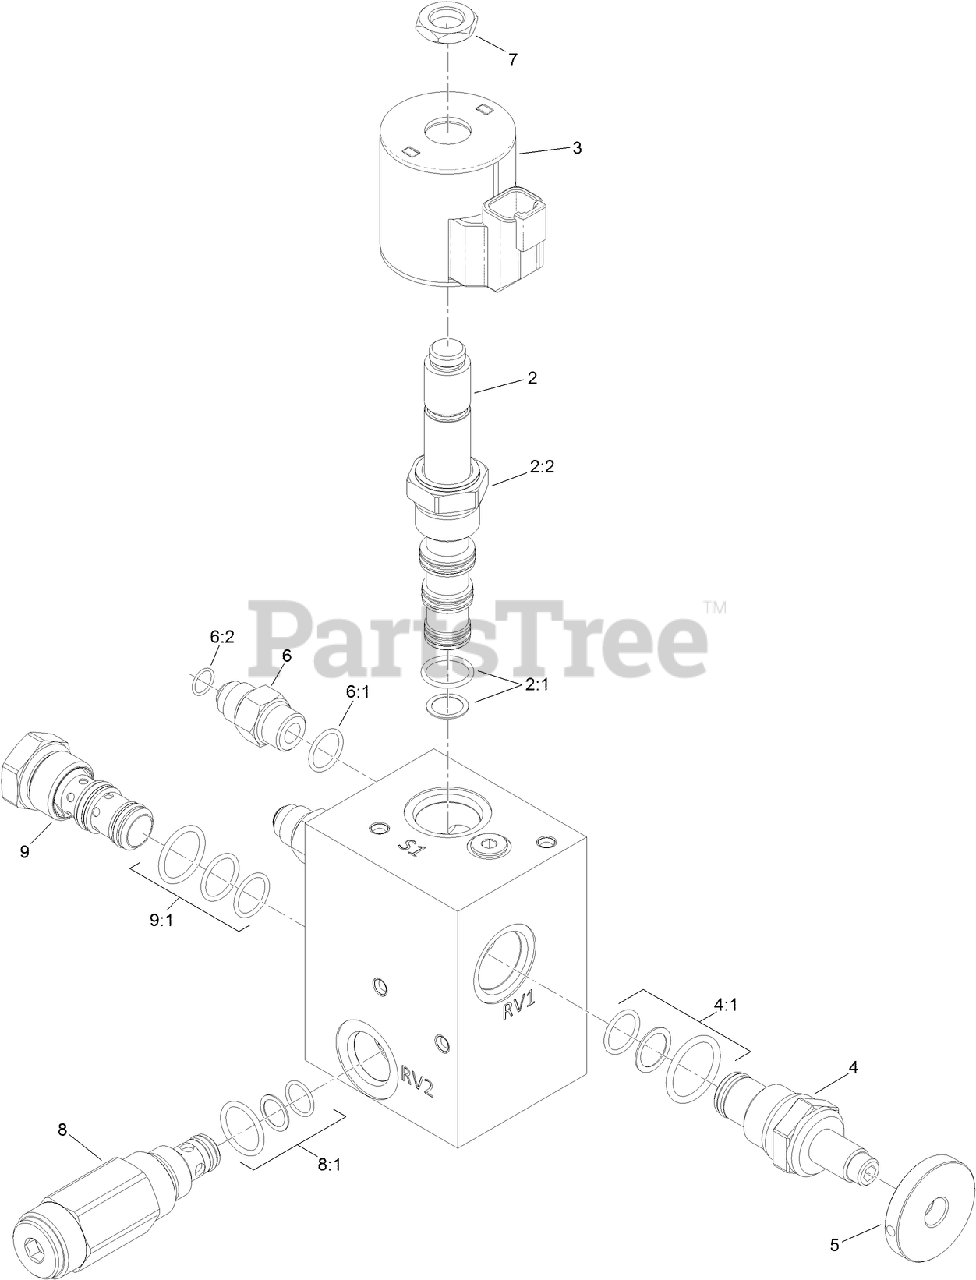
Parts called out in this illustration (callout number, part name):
2	VALVE-SOLENOID
2:1	SPOOL VALVE SEAL KIT
2:2	NUT-COIL
3	COIL-SOLENOID
4	VALVE-RELIEF, POPPET STYLE
4:1	RELIEF VALVE SEAL KIT
5	KNOB (1.5 DIA)
6	FITTING-STRAIGHT
6:1	O-Ring
6:2	O-RING
7	NUT-COIL
8	VALVE-RELIEF
8:1	SEAL KIT
9	VALVE-CHECK, P O
9:1	SEAL KIT
